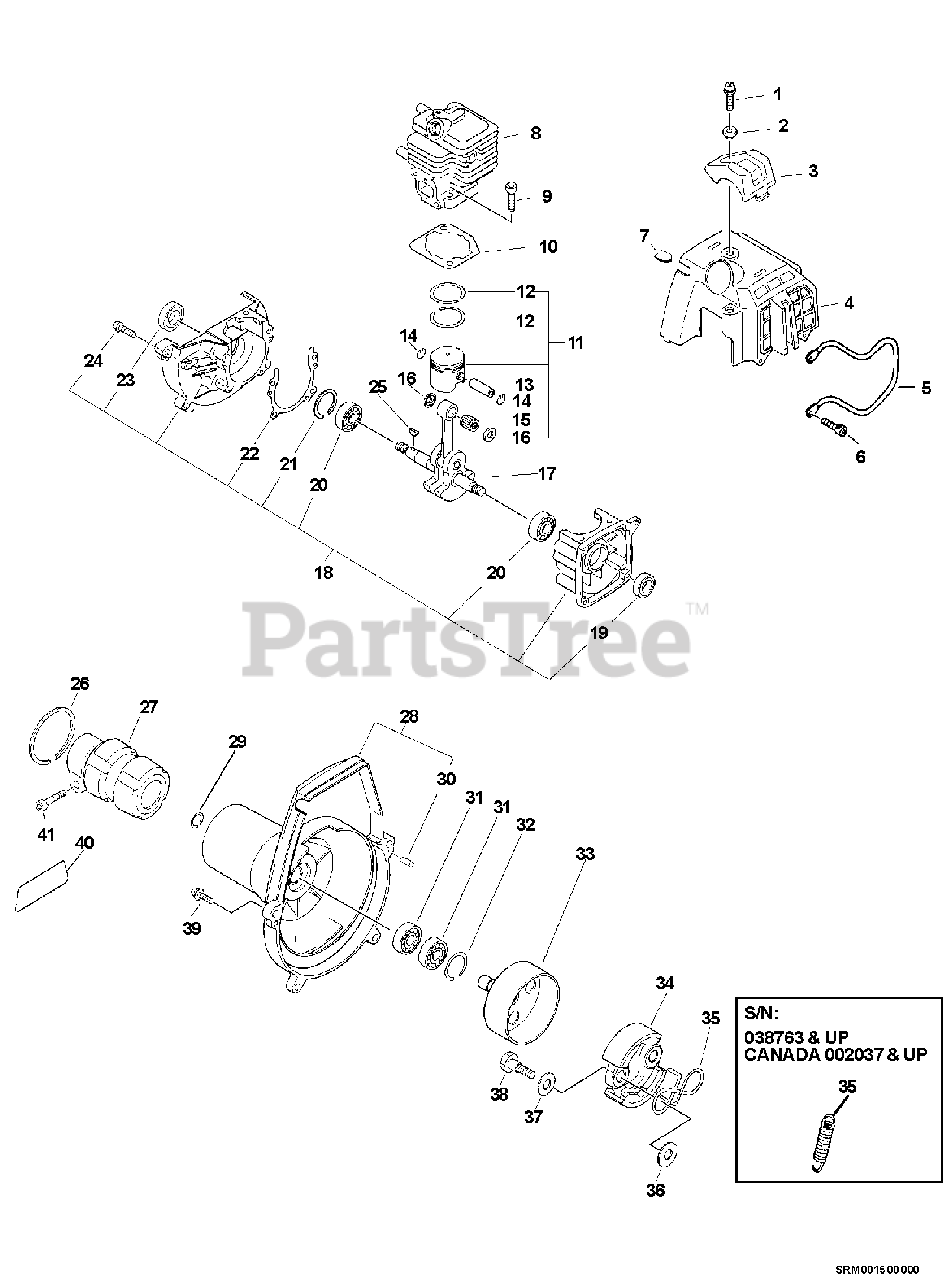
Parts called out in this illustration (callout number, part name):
1	SCREW - 5X20
2	COLLAR
3	GUARD - TOP
4	COVER, ENGINE
5	GUARD, ENGINE
6	SCREW - 4X16
8	CYLINDER
9	SCREW - 5X22
10	GASKET, CYLINDER
11	PISTON KIT
12	RING, PISTON
13	PIN, PISTON
14	RING, RETAINING
15	BEARING, NEEDLE
16	SPACER, PISTON
17	CRANKSHAFT ASSY
18	CRANKCASE KIT
19	SEAL, OIL
20	BEARING, BALL - 6001C3
21	RING, RETAINING - 28
22	GASKET, CRANKCASE
23	SEAL, OIL - 12
24	SCREW - 5X25
26	RING, RETAINING - 42
27	CLAMP, MAIN PIPE
28	FAN CASE KIT
28	FAN CASE ASSY
29	RING, RETAINING - 10
30	PIN - LOCATING
31	BEARING, BALL - 6000LU
32	RING, RETAINING - 26
33	DRUM, CLUTCH
34	SHOE, CLUTCH
35	SPRING, CLUTCH
36	WASHER - 6
37	WASHER - SPRING
38	BOLT, CLUTCH
39	SCREW - 5X18
40	LABEL - MODEL
41	SCREW - 5X28
